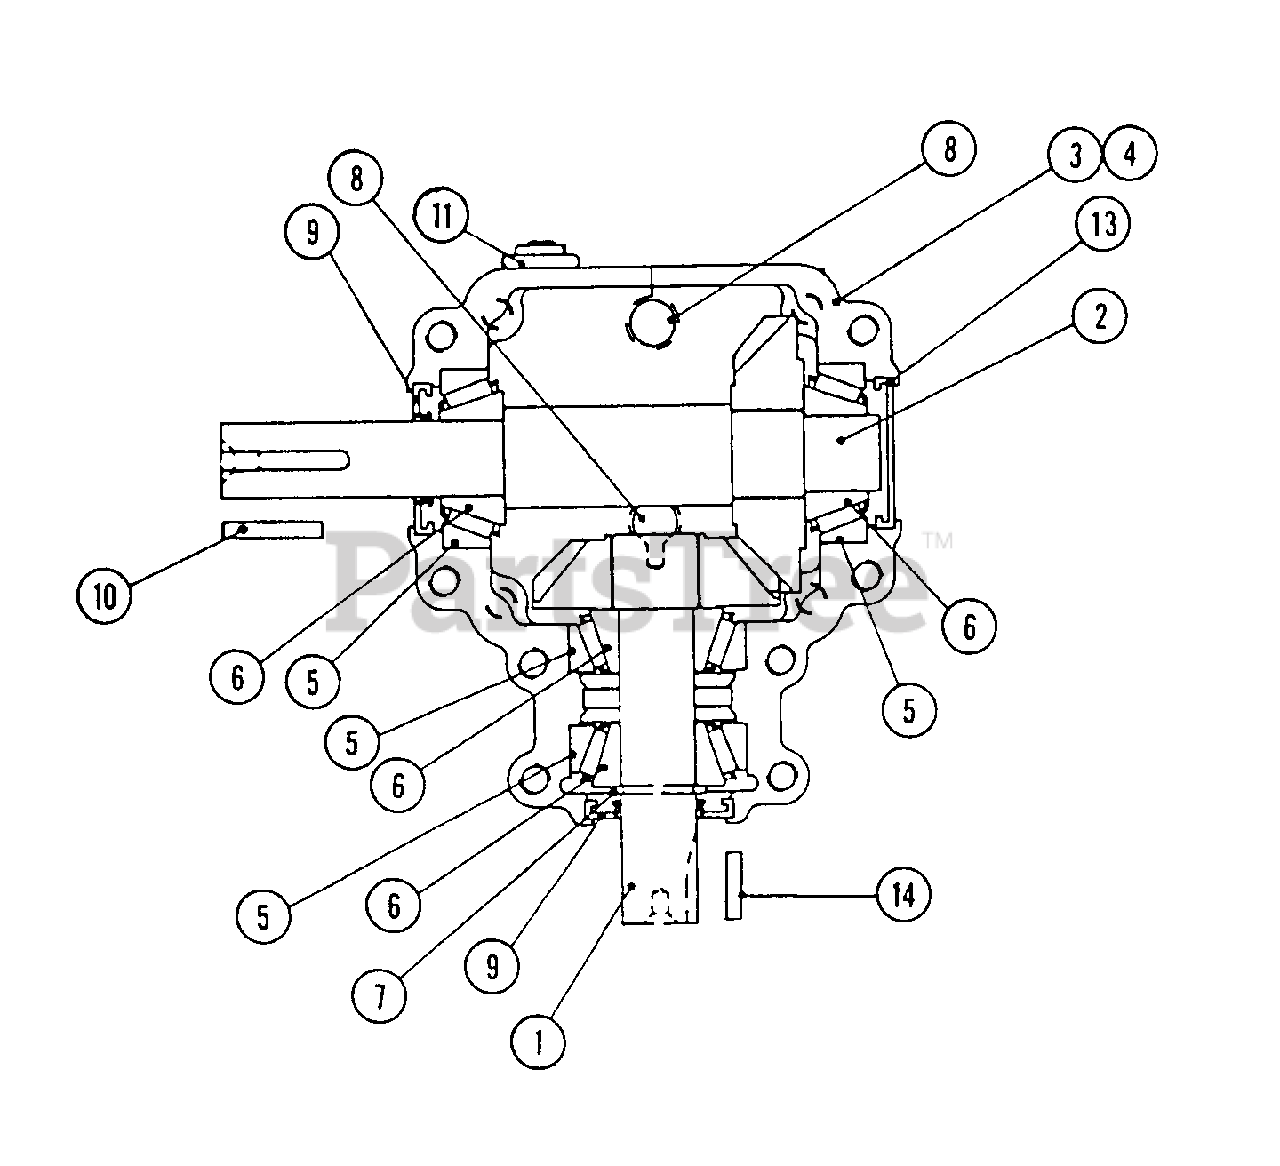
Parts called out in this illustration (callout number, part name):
1	SHAFT - pinion, with gear
2	SHAFT - cross, with gear
3	HOUSING - with tapped holes
5	CUP - bearing
6	CONE - bearing
7	RING - retaining
8	PLUG - pipe 1/4"
10	KEY - 3/16" x 1" input shaft
11	PIPE - vent
13	CAP - end
14	KEY - 3/16" x 5/8" output shaft
